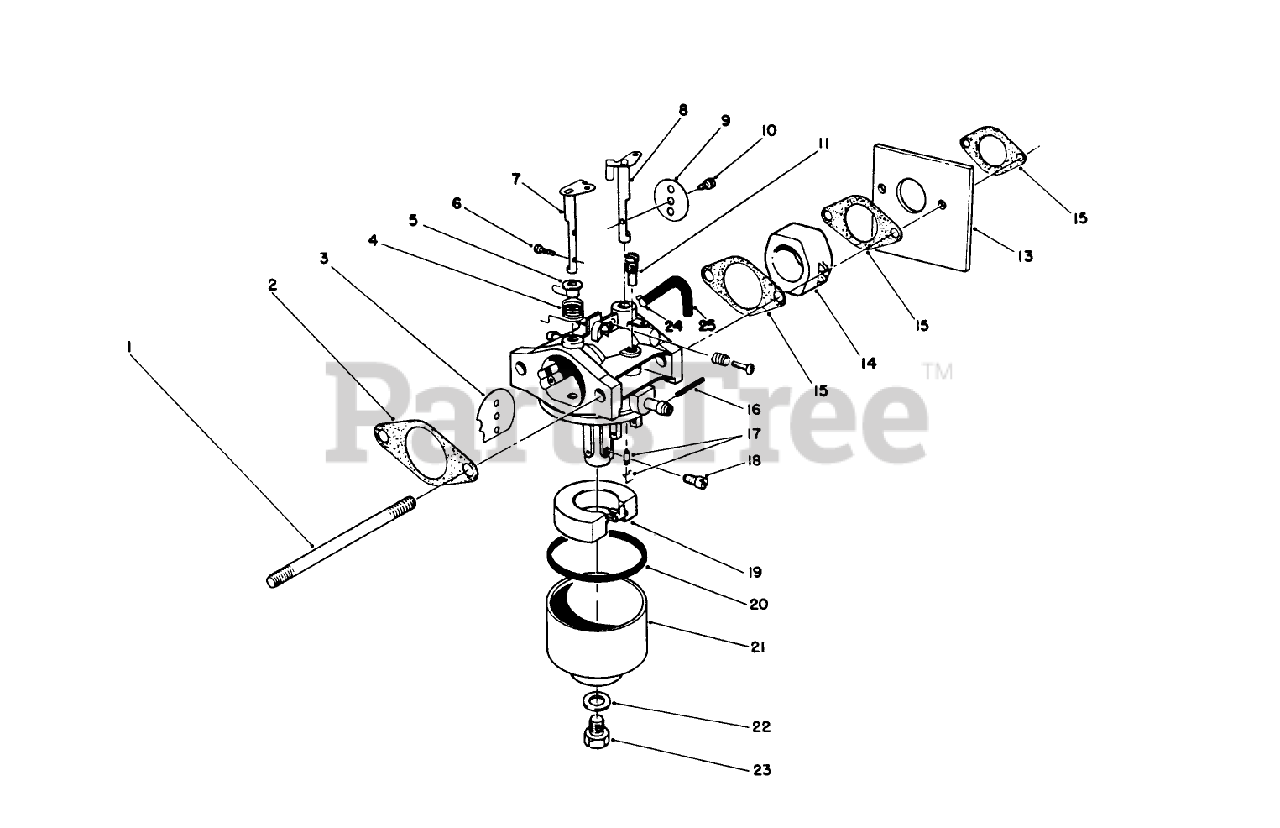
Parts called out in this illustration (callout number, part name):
1	STUD-CARBURETOR
2	GASKET-AIR CLEANER
5	BUSHING
6	SCREW
7	SHAFT-CHOKE
8	SHAFT
9	PLATE
11	PILOT JET
14	INSULATOR-CARBURETOR
15	GASKET-CARB
16	PIN-HINGE
17	NEEDLE
18	JET-MAIN
19	FLOAT
20	GASKET
21	BOWL - FLOAT
22	GASKET
23	SCREW
25	VENT TUBE
